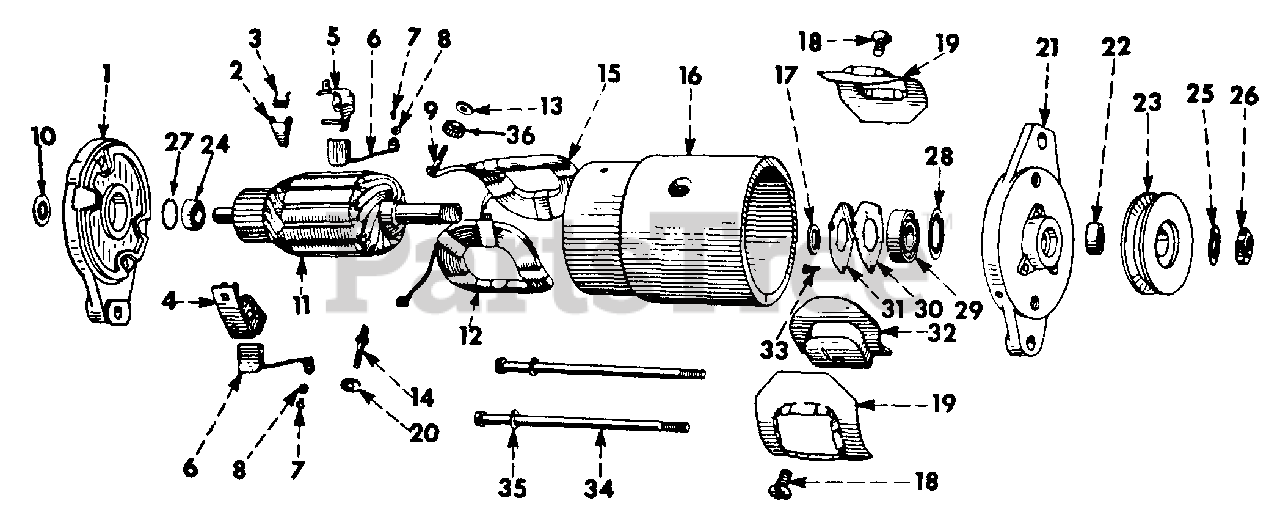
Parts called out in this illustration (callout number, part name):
1	FRAME ASSY, COMMUTATOR END
1	FRAME ASSY, COMMUTATOR END-FOR MOTOR GENERATOR, IH-1101432
3	SPRING, BRUSH
4	HOLDER, BRUSH INSULATED
5	HOLDER, BRUSH GROUND
6	BRUSH
7	SCREW, NO. 6 X 5/16 C-Z SLT-RD-HD MACH
8	WASHER, BRUSH LEAD ATTACHING SCREW LOCK
9	STUD, TERMINAL FIELD
10	PLUG, COMMUTATOR END BEARING WELL
11	ARMATURE
12	COIL, FIELD RH -SHUNT
13	WASHER, TERMINAL STUD INSULATING
14	STUD, TERMINAL ARMATURE
15	COIL, FIELD LH
16	FRAME
17	COLLAR, DRIVE END SPACE -INSIDE-
18	SCREW, POLE SHOE
19	INSULATOR, FIELD COIL
20	BUSHING, FIELD TERMINAL INSULATING -INSIDE-
21	FRAME, DRIVE END
22	COLLAR, DRIVE END SPACE
23	PULLEY, MOTOR GENERATOR
24	BALL BEARING, COMUTATOR END
25	WASHER, DRIVE END SHAFT NUT LOCK
26	NUT, DRIVE END SHAFT
27	CLAMP, COMMUTATOR END BEARING
28	PLATE, DRIVE END GREASE SLINGER
29	BALL BEARING, DRIVE END
30	GASKET, DRIVE END RETAINER PLATE
31	PLATE, DRIVE END RETAINER
33	SCREW, DRIVE END RETAINER PLATE
34	BOLT, THRU
35	WASHER, THRU BOLT
36	BUSHING, ARMATURE TERMINAL INSULATING
